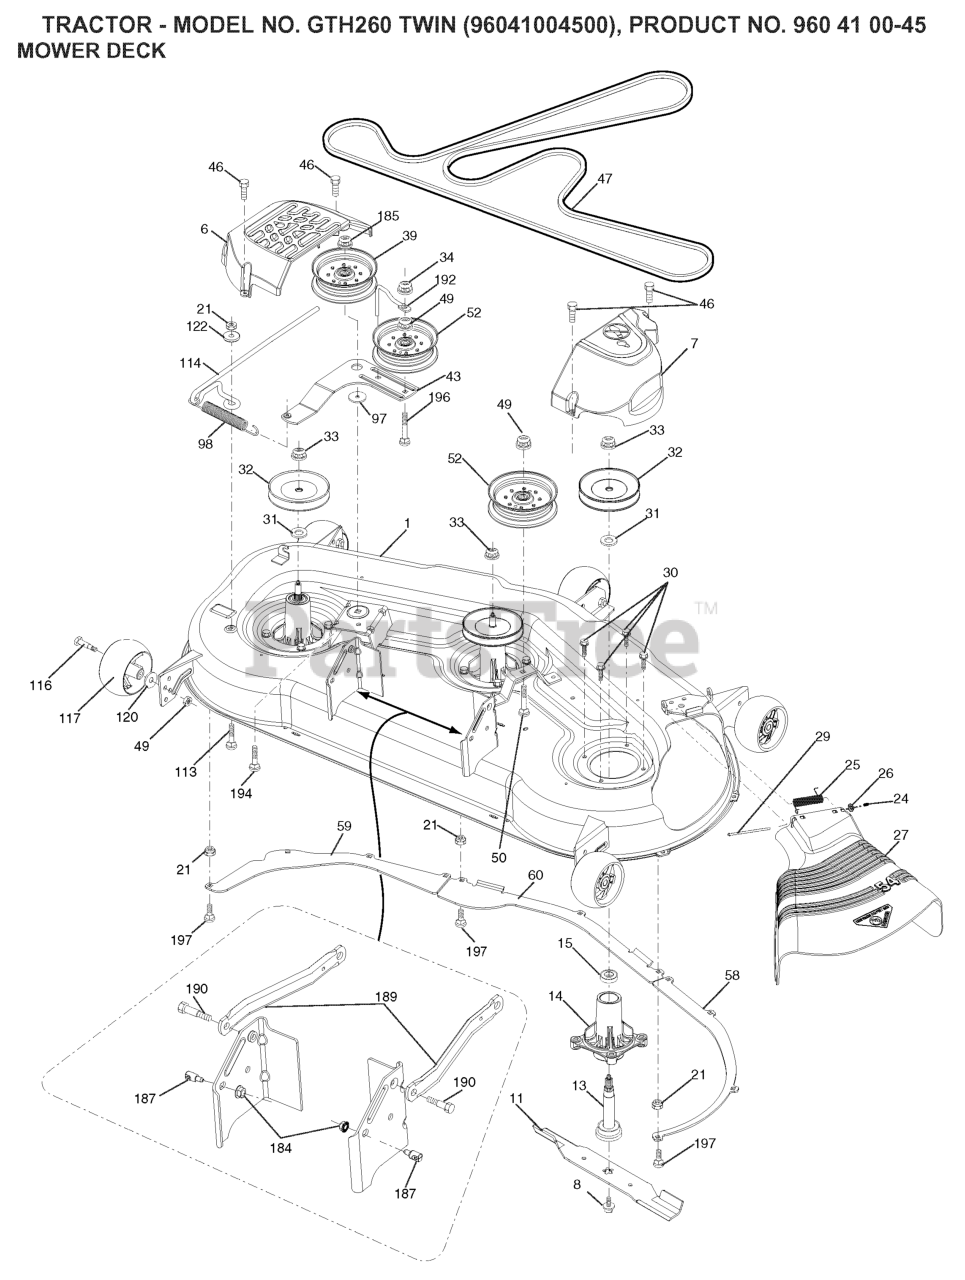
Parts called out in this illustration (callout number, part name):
1	DECK.WELDMENT.54'
6	COVER.MANDREL.LH.54"20
7	COVER.MANDREL.RH.54.20
8	BOLT 7/16 ASM BLADE
13	SHAFT ASM MANDREL
14	RP.HOUSING.MANDREL.4PT.
21	LOCKNUT
24	CAP-SLEEVE LT
25	SPRING, TORSION
26	NUT PUSH M
27	DEFLECTOR
29	ROD.HINGE
30	SCREW, WASHER HEAD
31	WASHER.SPACER.MANDREL
32	PULLEY/MANDREL
33	NUT.FLANGE.LOCK.TOP
39	RB PULLEY.IDLER.4.50/HUB SPEC
46	SCREW.1/4-20X5/8
47	RP.BELT.DRIVE.54."2006
49	NUT LOCK FLG 3/8-16 UNC
52	PULLEY.IDLER.2006
58	BAFFLE.RIGHT.54"
59	BAFFLE.LEFT.54"
60	BAFFLE CENTER 54" MOWER
98	SPRING, DECK DRIVE
114	ROD TENSION RELIEF
116	BOLT.SHOULDER.3/8-16X3-5/8.
117	RP WHEEL. GUAGE RALLY
120	WASHER
122	BUSHING.RELIEF.TENSION
184	NUT LOCK HEX FLANGE 5/16-18
185	NUT.LOCK.FLANGE.7/16
187	STUD.FASTNER.W/ANTI-ROTATE
189	ARM.SUSPENSION.MOWER
190	BOLT.SHOULDER
192	KEEPER.BELT.IDLER.54"T
194	BOLT.CARR.SQNK.7/16
